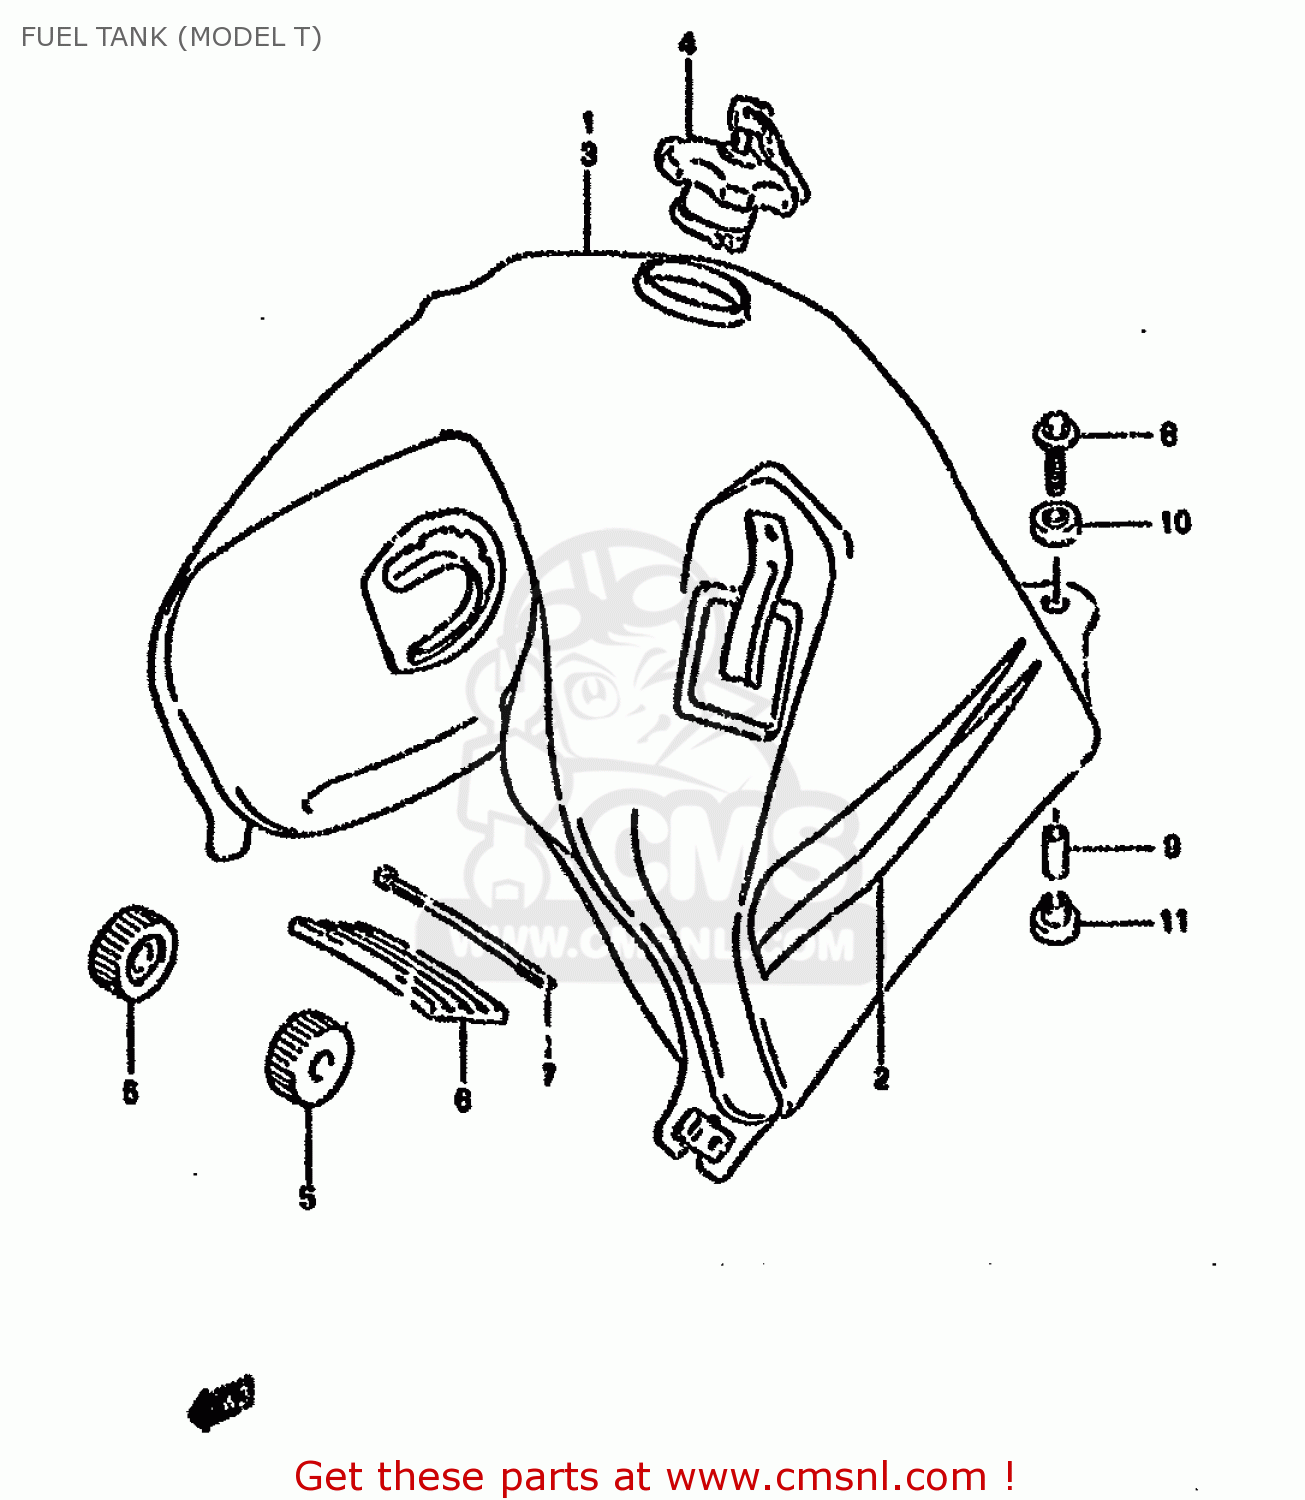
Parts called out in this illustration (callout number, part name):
1	TANK ASSY,FUEL (GREEN)
2	TAPE SET,FUEL TANK
3	TANK ASSY,FUEL (GREEN)
4	CAP SET,FUEL TANK
5	CUSHION,FUEL TANK FR
6	CUSHION,FUEL TANK UPR FR
7	CLAMP
8	BOLT(6X30)
9	SPACER
10	CUSHION
11	CUSHION
